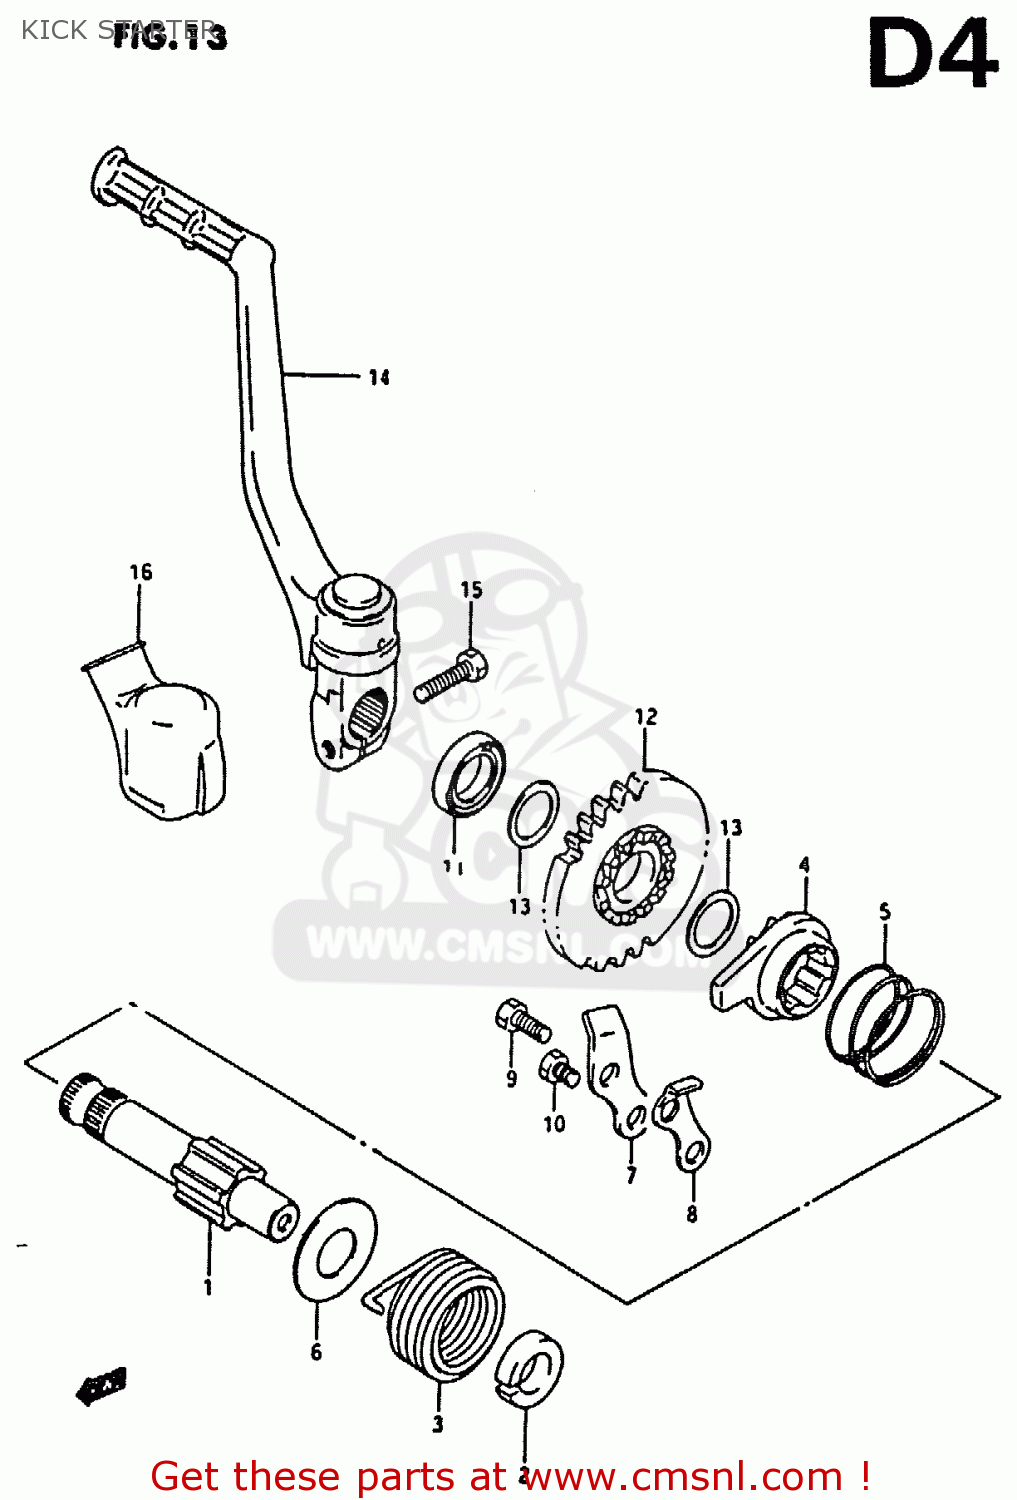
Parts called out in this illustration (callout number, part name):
1	SHAFT,KICK STARTER
2	GUIDE,SPRING
3	SPRING
4	STARTER,KICK
5	SPRING
6	WASHER
7	GUIDE,KICK STARTER
8	STOPPER,KICK STARTER
9	BOLT
10	BOLT 6X8
11	SEAL,OIL(14X24X6)
12	GEAR,KICK STARTER DRIVE
13	WASHER
14	LEVER ASSY,KICK STARTER
15	BOLT
16	COVER,KICK LEVER JOINT
